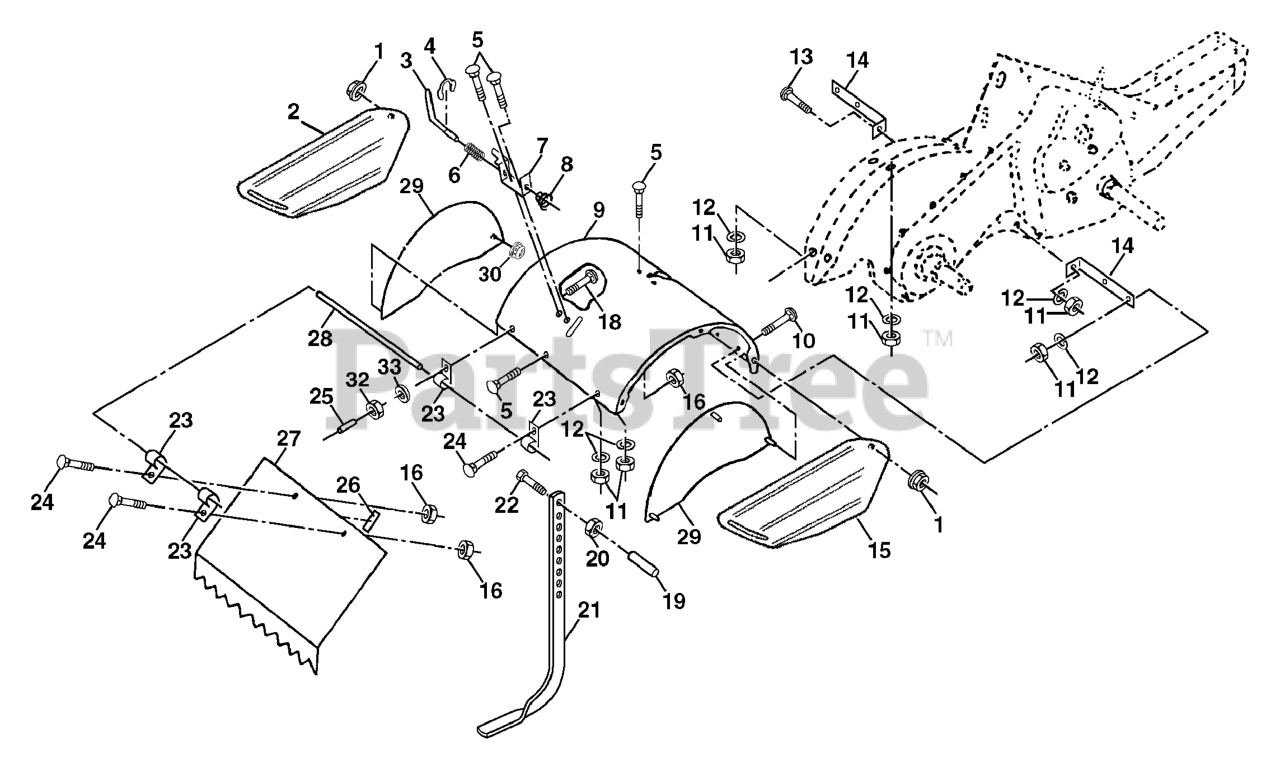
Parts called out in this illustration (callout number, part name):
1	NUT LOCK HEX FLANGE 5/16-18
2	SHIELD
3	STAKE PIN TI
4	KLIP RING TI
5	RP BOLT 5/16-18 X3/4 ZN/YEL GR
7	BRACKET.LATCH.STAKE.3.20.BLACK
8	SPRING CRT
9	SHIELD
10	BOLT
11	NUT
12	WASHER.LOCK.HVY.HLCL.SPR.5/16
13	BOLT.CARRIAGE.5/16-18
14	BRACKET.TINE.SHIELD.TILLER.BLA
15	SIDE SHIELD RH
16	NUT T
20	NUT.HEX.3/8-16UNC
21	STAKE.DEPTH.16.CRT.BLACK
22	BOLT.375-16
24	BOLT
25	VINYL CAP TI
26	PAD IDLER TI
27	SHIELD LEVELING
28	PIN.HINGE.TILLER
29	SIDE SHIELD
30	LOCKNUT-FLANGE 5/16-18
32	NUT
33	LOCKWASHER
